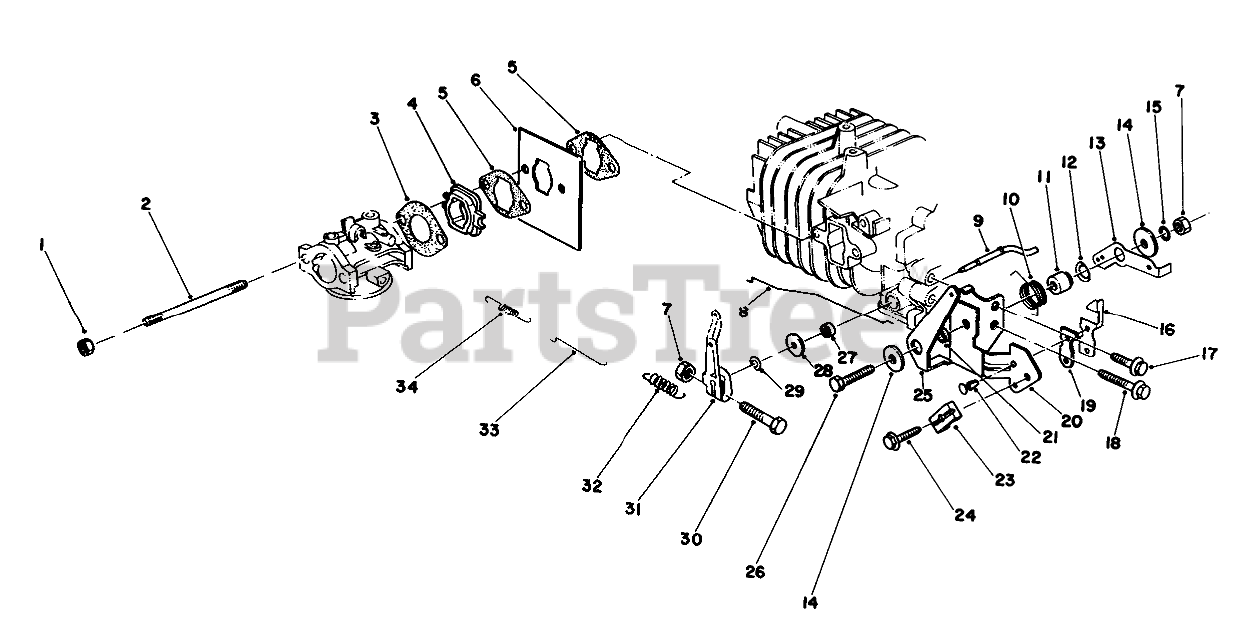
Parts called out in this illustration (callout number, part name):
1	NUT-LOCK
2	CARB STUD BOLT
3	GASKET-CARB
4	INSULATOR
5	GASKET
6	SHIELD
8	CHOKE ROD
9	Shaft-Govemor
10	Spring-Choke Control Lever
11	Gov Lever Spacer
12	Washer-Gov. Spring Lever
13	GOV SPRING LEVER
14	WASHER
15	LOCKWASHER
16	TERMINAL-KILL SWITCH
19	INSULATOR-KILL SWITCH
20	Bracket-Throttle Control
21	Spacer-Choke Control Lever
22	KILL SWITCH RIVET
23	CLAMP-CABLE
25	LEVER-CONTROL, CHOKE
27	SEAL-OIL
28	WASHER
29	E-RING
31	Lever-Throttle Control
32	GOVERNOR SPRING
33	ROD-CARBURETOR
34	SPRING
